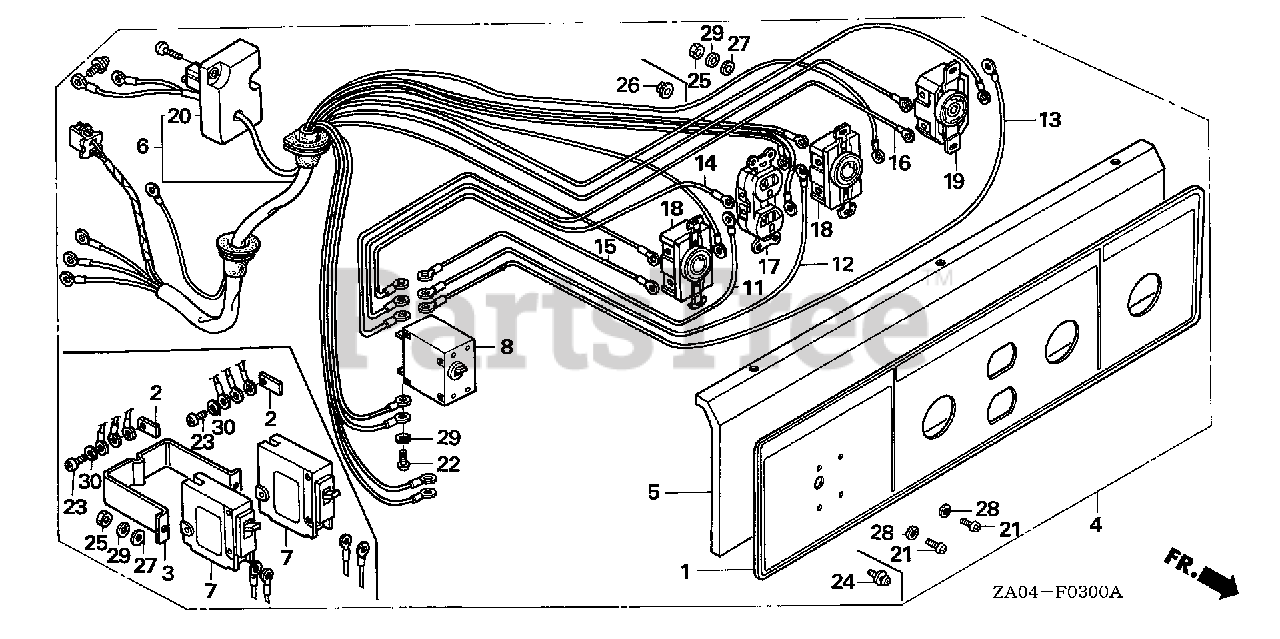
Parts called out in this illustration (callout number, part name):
1	MARK, RECEPTACLE PANEL
4	PANEL ASSY., RECEPTACLE *B9* (ATLANTIS BLUE)
5	PANEL, RECEPTACLE *B9* (ATLANTIS BLUE)
6	WIRE HARNESS ASSY., RECEPTACLE
8	BREAKER, CIRCUIT (22A)
11	WIRE, RECEPTACLE CIRCUIT BREAKER CONNECTING
12	WIRE, RECEPTACLE CIRCUIT BREAKER CONNECTING
13	WIRE, RECEPTACLE CIRCUIT BREAKER CONNECTING
14	WIRE, RECEPTACLE CIRCUIT BREAKER CONNECTING
15	WIRE, RECEPTACLE CIRCUIT BREAKER CONNECTING
16	WIRE, RECEPTACLE CIRCUIT BREAKER CONNECTING
17	RECEPTACLE (20A/125V) (EAGLE / RONG FENG)
18	RECEPTACLE (20A/125V) (NOT AVAILABLE)
19	RECEPTACLE (30A/125-250V)
20	CONTROL UNIT, IDLE
22	SCREW, PAN (4X8)
24	SCREW-WASHER (3X6)
26	NUT, FLANGE (4MM)
29	WASHER, SPRING (4MM)
